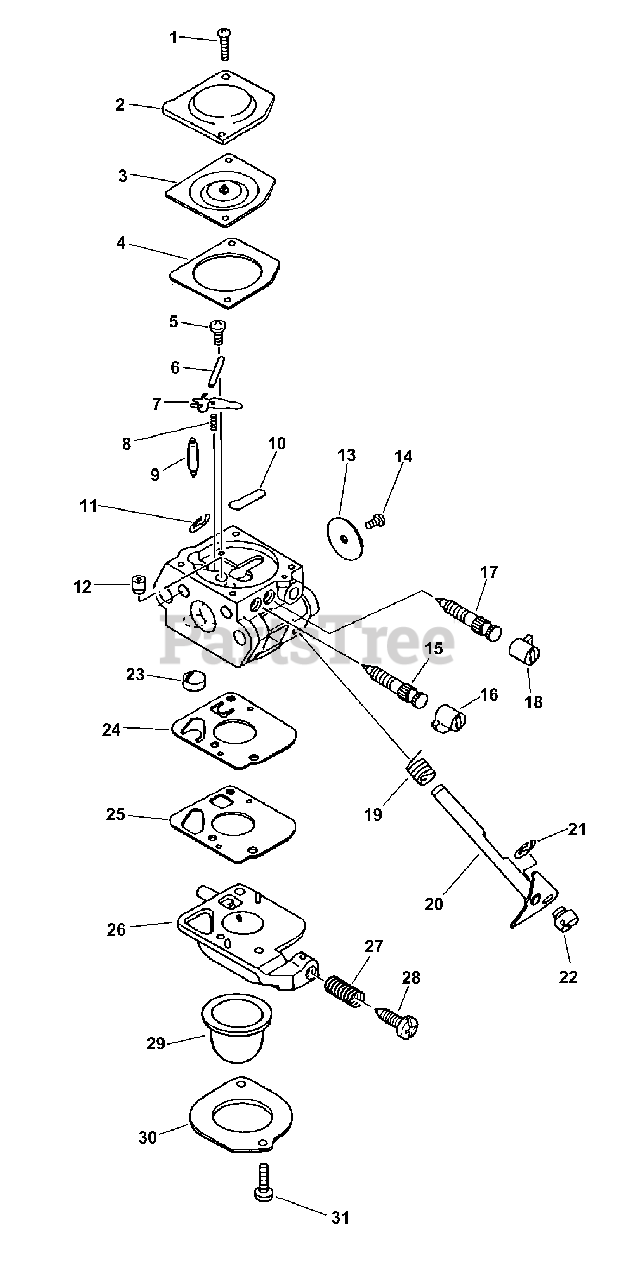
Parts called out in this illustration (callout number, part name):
1	SCREW
2	COVER, METERING
3	DIAPHRAGM, METERING
4	GASKET, METERING
5	SCREW, METERING LEVER PIN
6	PIN, METERING LEVER
7	LEVER, METERING
8	SPRING, METERING LEVER
9	VALVE, NEEDLE
10	PLUG, WELCH
11	RING, RETAINING
12	NOZZLE, CHECK VALVE
13	VALVE, THROTTLE
14	SCREW
15	NEEDLE - HIGH SPEED
16	CAP, LIMITER
17	NEEDLE - LOW SPEED
18	CAP, LIMITER
19	SPRING, RETURN
20	SHAFT, THROTTLE
21	RING, RETAINING
22	SWIVEL
23	STRAINER
24	DIAPHRAGM, PUMP
25	GASKET, PUMP
26	BASE, PURGE
27	SPRING, IDLE ADJUST
28	SCREW, IDLE ADJUST
29	BULB, PURGE
30	RETAINER, PURGE BULB
31	SCREW, RETAINER
